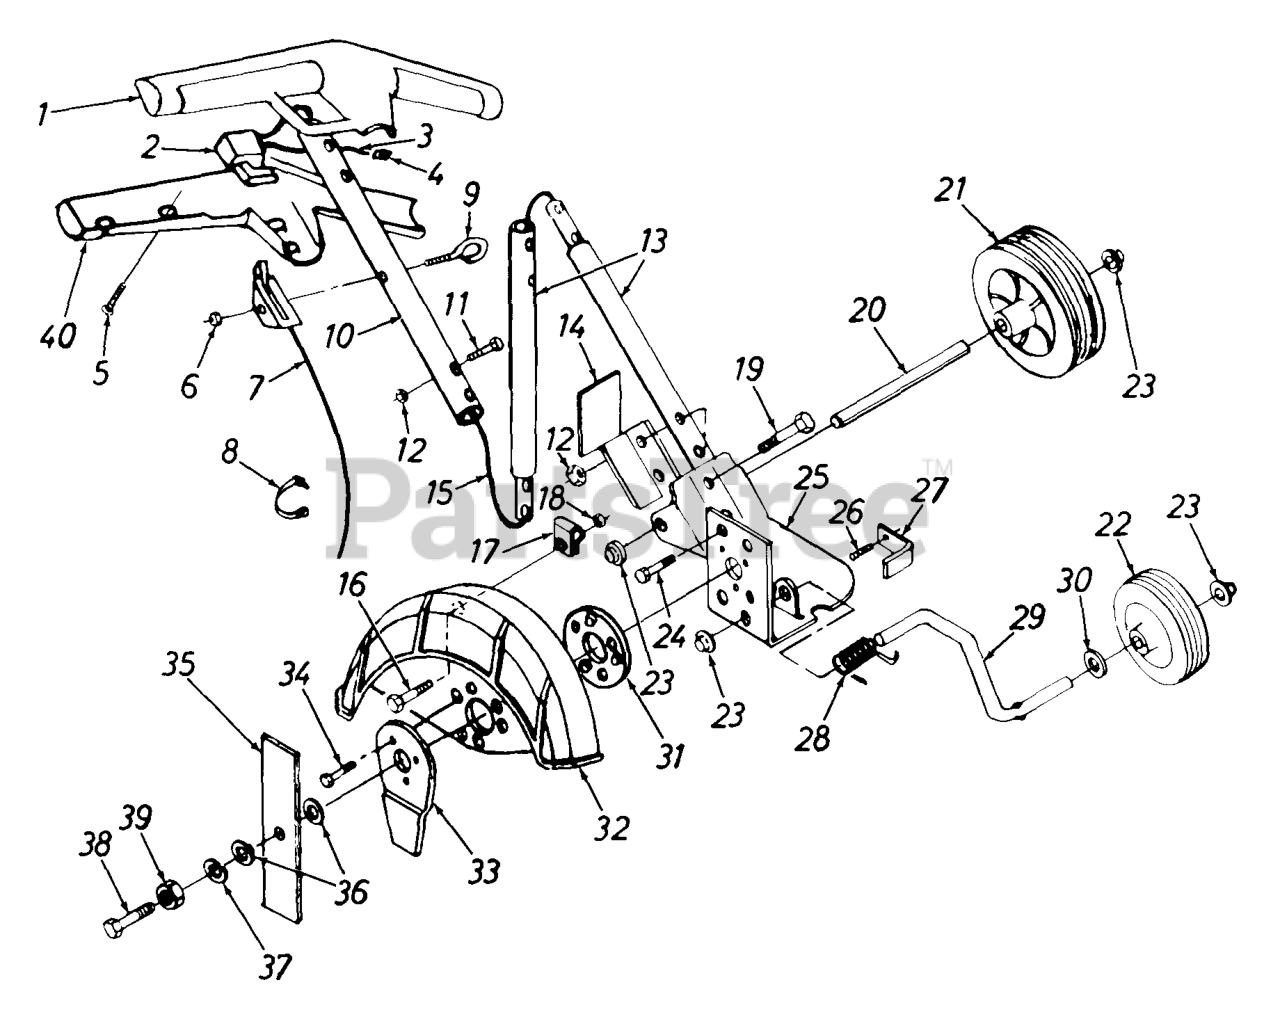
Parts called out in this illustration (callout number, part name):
1	Handle - Switch Housing (Upper)
2	Engine Switch
3	Ground Wire
4	Ground Clip
5	Pan Scr. #8 x .62" (Special)
6	Hex Lock Nut 1/4-20 Thd.
7	Choke Control Ass'y.
8	Cable Tie
9	Rope Guide Eyebolt
10	Upper Handle Tube
11	Hex Bolt #10-24 x 1.25" Lg.
12	Hex Ins. E-Nut #10-24 Thd.
13	Lower Handle Tube
14	Muffler Deflector Brkt.
15	Engine Wire Ass'y.
16	Hex Bolt 1/4-20 x .5" Lg.
17	Choke Clip
18	Hex L-Nut 1/4-20 Thd.
19	Hex Bolt #10-24 x 1.5" Lg.
20	Axle Pin
21	5" Wheel
22	4" Wheel
23	Push Nut
24	Hex Wash. Hd. Scr. 1/4-20 x .5" Lg.
25	Frame Base
26	Self-Tap Scr. #8-32 x .62"
27	Nose Wheel Stop Brkt.
28	Spring - Nose Wheel
29	Nose Wheel Axle
30	Fl-Wash. 318" I.D. x .875" O.D.
31	Spacer - Blade Guard
32	Blade Guard
33	Edge Guide
34	Self-Tap Scr. 410-32 x .75" Lg.
35	9" Blade
36	Bell-Wash. 3/8" I.D.
37	L-Wash. 3/8" I.D.
38	Hex Bolt 3/8-24 x 1.25" (Gr. 5)
39	Hex Nut 3/8-24 Thd.
40	Handle - Switch Housing (Lower)
